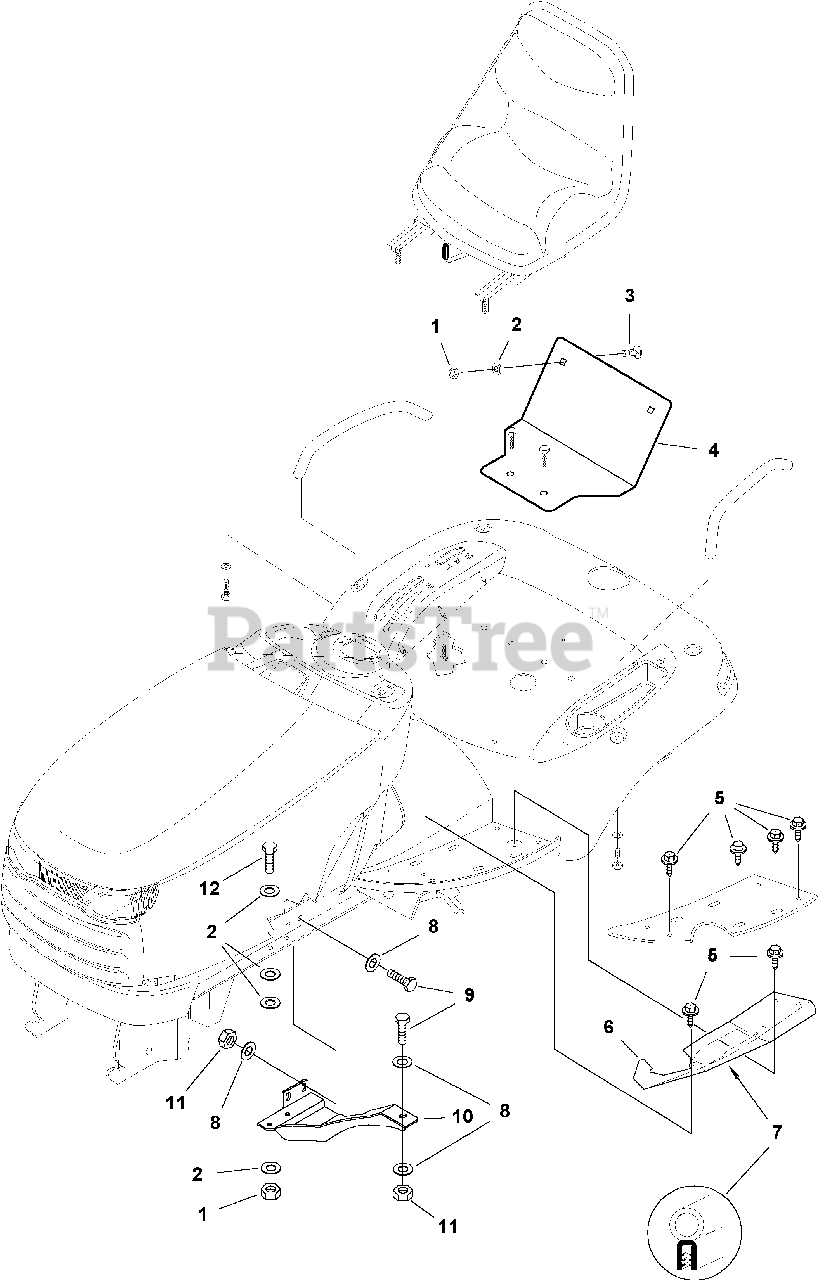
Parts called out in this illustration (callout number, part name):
4	CONSOLE, Rear
6	SHEET WIDENING, Left Bottom
6	SHEET WIDENING, Right Bottom
7	PROFILE SEALING, 4 ft. 4 in.
10	CONSOLE, Front Left
10	CONSOLE, Front Right
